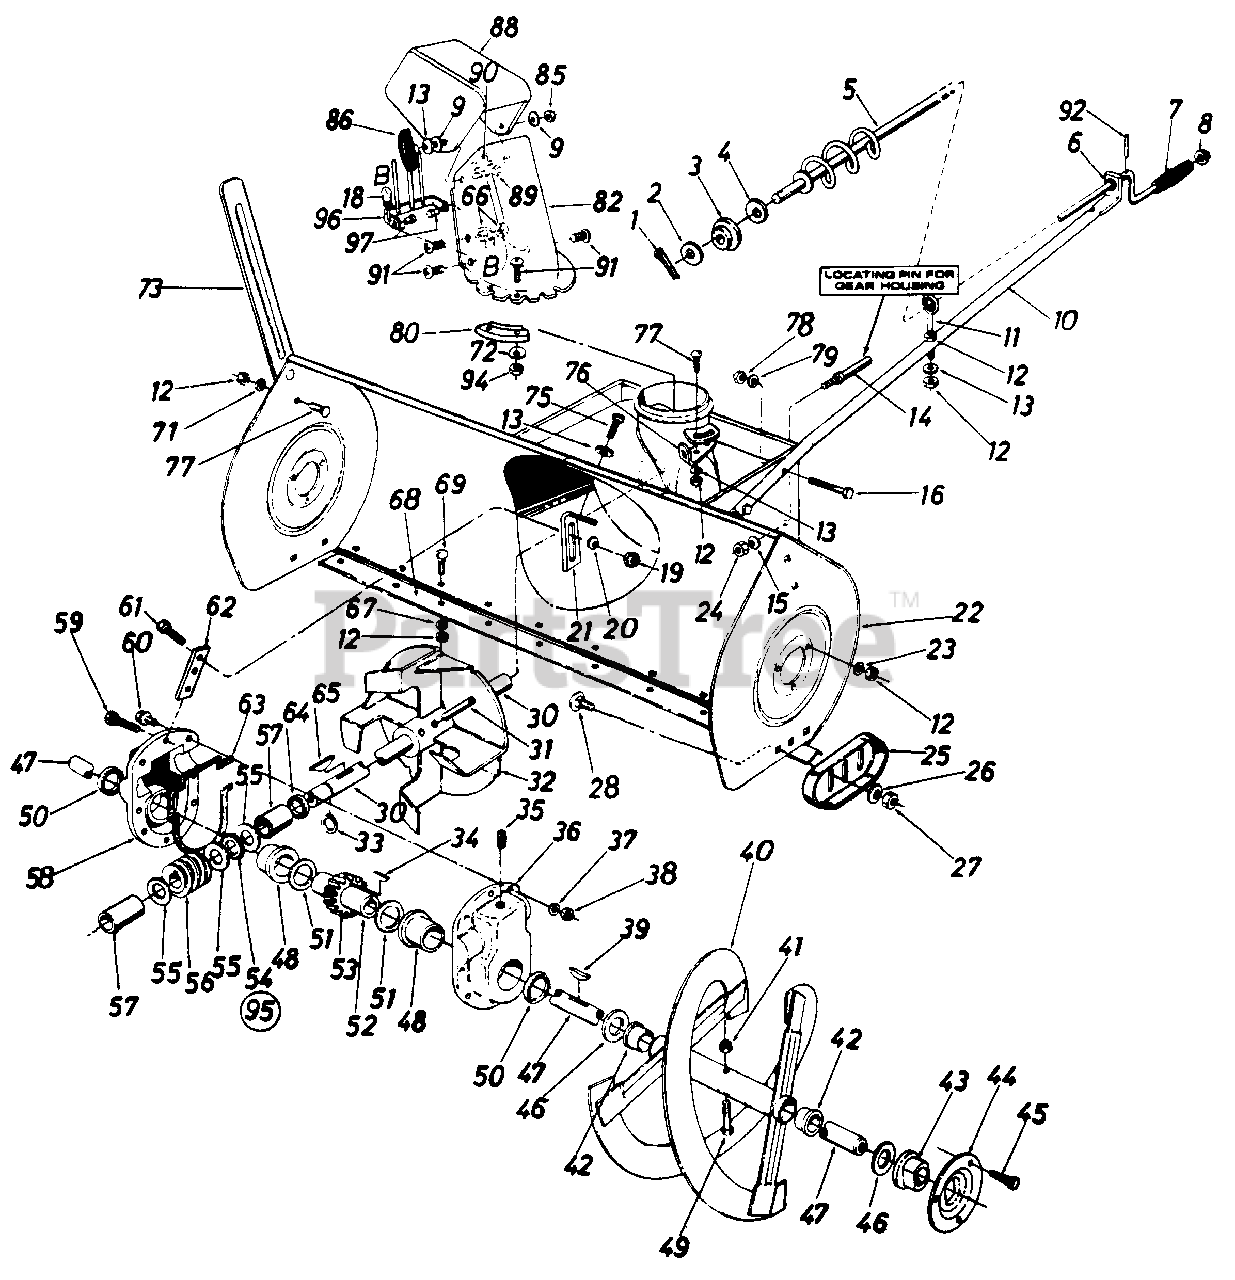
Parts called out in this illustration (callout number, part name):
1	Cotter Pin
2	Fl.-Wash. .39" I.D. x .62" O.D.
3	Plastic Bushing
4	Fl.-Wash. .385" I.D. x .62" O.D.
5	Chute Crank Ass'y.
6	Plastic Bushing
7	Knob (Black)
8	Push Nut 3/8" Rod
9	Fl.-Wash. .344" I.D. x 1.25" O.D.
10	Chute Crank Support Tubing
11	Eyebolt
12	Hex Nut 5/16-18 Thd.
13	Bell.-Wash. .345" I.D. x .88" O.D.
14	Stud 3/8-16 x 2.75" Lg.
15	Bell.-Wash. .400" I.D. x .88" O.D.
16	Hex Bolt 3/8-24 x 1.25" Lg.
18	Extension Spring
19	Hex Nut 1/4-28 Thd.
20	Bell.-Wash. .265" I.D. x .75" O.D.
22	45" Snow Blower Housin Ass'y.
23	L.-Wash. 5/16" I.D.
24	Hex Jam Nut 3/8-16 Thd.
25	Slide Shoe
26	Bell.-Wash. .400" I.D. x .88" O.D.
27	Hex Jam Nut 3/8-16 Thd.
28	Carriage Bolt 3/8-16 x .62" Lg.
30	Blower Axle .875" Dia. x 14.75" Lg.
31	Spring Pin Spir. 5/16" Dia. x 1.75 Lg.
34	91 Woodr-Key 1/4 x 3/4" Dia. (HDN)
35	Vent Plug
36	Gear Hsg. Half L.H.
37	Spr.-Wash. .32" I.D. x .62" O.D.
38	Hex Ins. L.-Nut 5/16-18 Thd.
39	#91 Woodr-Key 1/4 x 3/4" Dia. (HDN)
41	Hex Ins. L.-Nut 5/16-18 Thd.
42	Plastic Bushing
43	Flange Brg. w/flats 1" I.D.
44	Bearing Housing
45	Hex Sems Bolt 5/16-18 x .75" 4.
46	Fl.-Wash. 1.00" I.D. x 1.75" O.D.
47	Spiral Axle
48	Flange Bearing 1.503" I.D.
49	Shear Bolt 5/16-18 x 1.75" Lg.
50	Oil Seal 1.50" I.D.
51	Fl.-Wash. 1.50" I.D. x 2.00" O.D.
52	Worm Gear Shaft
53	Double Threaded Worm Gear-L.H.
54	Thrust Brg. - .88" I.D. x 1.44" O.D.
55	Fl.-Wash. .88" 1 .D. x 1.4" O.D.
56	Double Threaded Worm-L.H.
57	Sleeve
58	Gear Hsg. Half - R.H.
59	Hex Bolt 5/16-18 x 1.25" 4.
60	Hex Bolt 5/16-18 x 1.0" 4. (Grade 5)
61	Hex Bolt 1/4-28 x .75" Lg.
62	Gear Housing Support Plate
63	Rubber Gasket
64	Oil Seal - .875" I.D.
65	#9 Hi-Pro Key 3/16 x 3/4" Dia. (HT.)
66	Hex L-Nut 1/4-20 Thd.
67	L.-Wash. 5/16" I.D.
69	Carriage Bolt 5/16-18 x 1.00" Lg.*
71	L-Wash. 5/16" I.D.
72	Fl.-Wash. 1/4" I.D.
73	Guide Blade
75	Hex Wash. Hd. AB Tap Scr. 5/16" x .75" Lg.
77	Carriage Bolt 5/16-18 x .75" Lg.*
78	Hex Ins. L.-Nut 3/8-24 Thd.
79	L.-Wash. 3/8" I.D.
80	Chute Flange Keeper
82	Lower Chute
85	Hex Cent. L.-Nut 5/16-18 Thd.
86	Knob Handle
88	Upper Chute
89	Carriage Bolt 5/16-18 x 1.00" Lg.*
90	Truss Mach. Scr. 5/16-18 x .75" Lg.
91	Truss Mach. Scr. 1/4-20 x .75"
92	Roll Pin .12" Dia. x .63"
94	Hex Cent. L-Nut 1/4-20 Thd.
95	Gear Box Ass'y.-Comp.
97	Shld. Nut 1/4-20 Thd.
